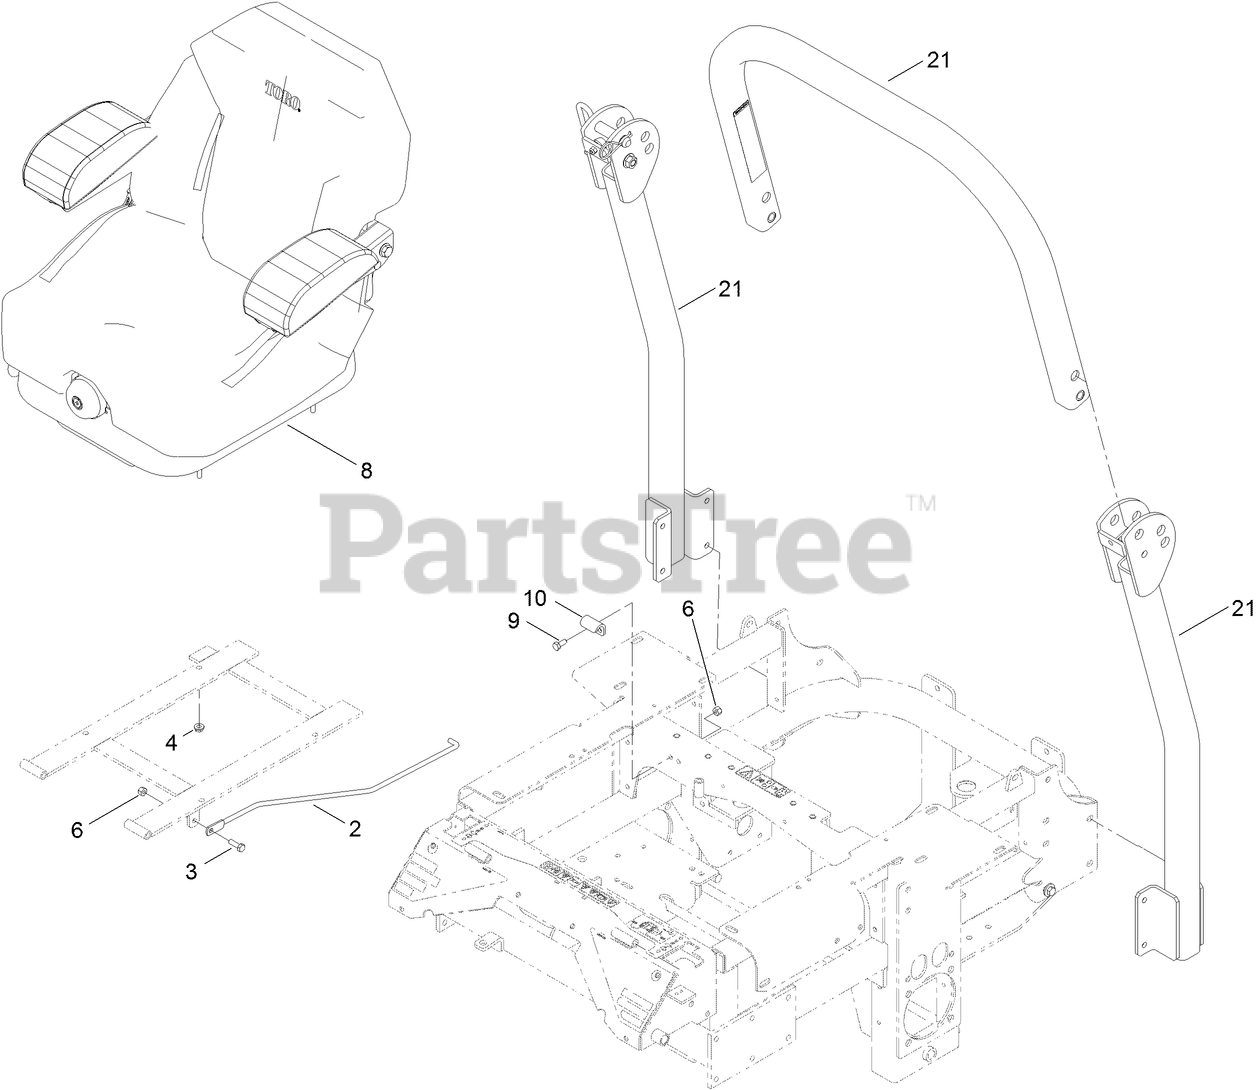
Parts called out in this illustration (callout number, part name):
2	ROD-PROP, SEAT
3	SCREW-HH
4	NUT-HF
6	NUT-LOCK, NI
8	SEAT-SUSPENSION
9	SCREW-HH
10	CATCH-LATCH, SEAT
21	ROPS KIT
